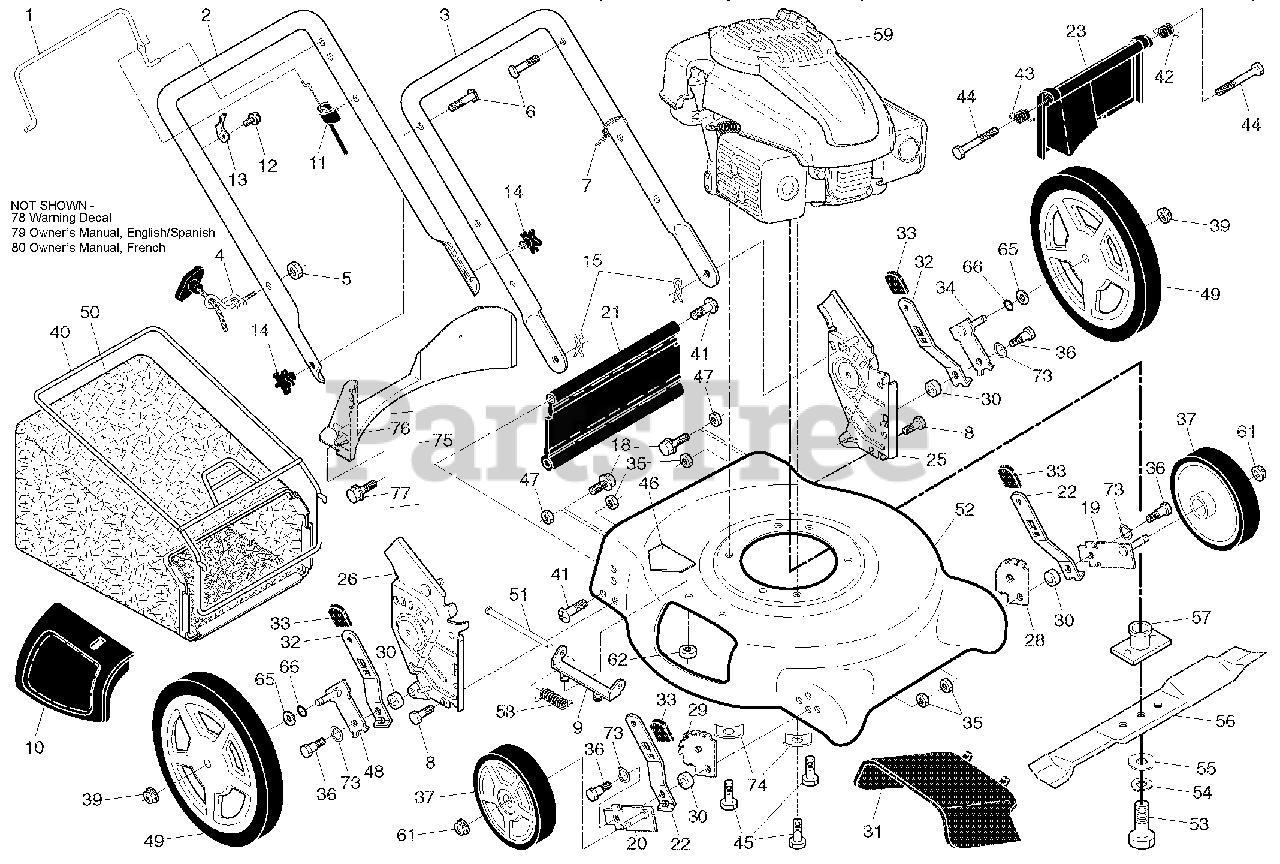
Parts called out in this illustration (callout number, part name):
1	Control Bar
2	Upper Handle
3	Lower Handle
4	Rope Guide
5	Nut, Hex
6	Handle Bolt
7	Wire Tie
8	Bolt, Hex Head 5/16-18 x 3/4
9	Hinge Bracket
10	Mulcher Door
11	Engine Zone Control Cable
12	Hex Washer Head Screw
13	Up-Stop Bracket
14	Handle Knob
15	Hairpin Cotter
18	SCREW.HEX.WASHEAD.1/4-20 X 3/8
19	Axle Arm Assembly, Front, LH
20	Axle Arm Assembly, Front, RH
21	Kit, Rear Skirt
22	Selector Spring, Front
23	Rear Door Assembly
25	Handle Bracket Assembly, LH
26	Handle Bracket Assembly, RH
28	Wheel Adjusting Bracket, LH
29	Wheel Adjusting Bracket, RH
31	Discharge Deflector
32	Selector Spring, Rear
33	Selector Knob
34	TRANSAX HYGR G7-BCBB-1XDC-IECX
35	Locknut, Hex 5/16-18
36	Shoulder Bolt
37	Wheel & Tire Assembly, Front
39	Flanged Locknut, Hex
40	Frame, Grassbag
41	Hinge Screw
42	Spring, Rear Door, LH
43	Spring, Rear Door, RH
44	Bolt, Rear Door
45	Screw, Hex Head, Threaded, Rol
46	Danger Decal
47	Nut, Hex
48	Axle Arm Assembly, Rear, RH
49	Wheel & Tire Assembly, Rear
50	Grassbag
51	Hinge Rod
52	Kit, Lawn Mower Housing (Inclu
53	Screw, Hex Head, Grade 8 3/8-2
54	Helical Lockwasher
55	Hardened Washer
56	21" Blade
57	Blade Adapter
58	Hinge Spring
59	Engine, Kohler, Model Number XT173-3225-EA (For engine service and replacement parts,
61	Nut, Hex
62	Locknut, Hex 1/4-20
65	Washer, Flat
73	Washer, Curved, Cylindrical
74	Washer, Special, Engine
75	Kit, Rear Baffle (Includes 3 S
76	Baffle, Rear
77	Screw, Rear Baffle
79	OWNER'S MANUAL, ENG/SPA
80	Owner's Manual, French
